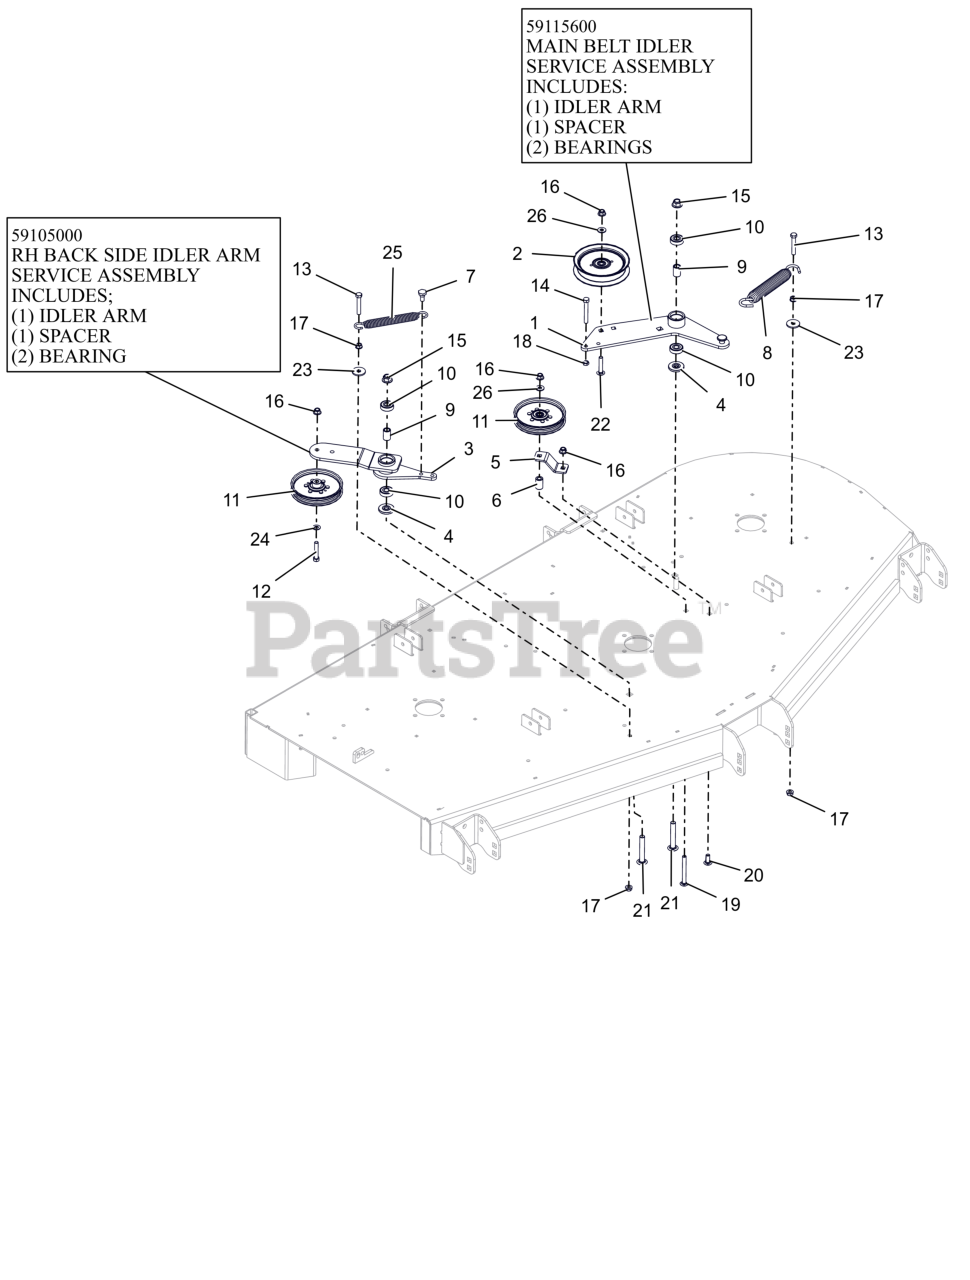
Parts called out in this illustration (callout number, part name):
1	WLDMT, DECK PTO IDLR ARM
1	ASSEMBLY, MAIN BELT IDLER
2	IDLER, FLAT 5.00"
3	WLDMT, DECK RH IDLER ARM
3	RH BACKSIDE IDLER ARM ASSEMBLY
4	SPACER, IDLER ARM
5	PTO FIXED IDLER MTG BRKT -RED
6	BUSHING, SLV .380X.750X1.190
7	BLT,SHLDR EP .38-16X.30 HEX YZ
8	SPRING, EXTENSION
9	SPACER .510 X .75 X 1.1485
10	BRG-BALL .500X1.38X.437
11	PULLEY, FLAT IDLER
12	BLT,HEX .38-16X2.00 G5 ZCC
13	BLT,HEX .38-16X2.25 G5 ZCC
14	BLT, HEX .38-16X2.75 G5 ZCC
15	NUT,NYL-FLG .50-13 GF ZCC
16	NUT,NYL-FLG .38-16 GF ZCC
17	NUT, SPNLK-FLG .38-16 G5 ZCC
18	NUT-JAM .375-16 G2 ZCC
19	BLT,RHSSN .38-16X3.50 G5 ZCC
20	BLT,RHSSN .38-16X1.00 G5 ZCC
21	BTL,RHSSN .500-13 X 3.25 G5 ZCC
22	BLT,RHSSN.375-16X2.00 G5 ZCC
23	WSHR,FLT .406X1.375X.135 ZCC
24	WSHR,FLT .406X.812X.065 ZCC
25	SPRING, EXTENSION
26	WSHR,FLT .375X.875X.083 ZCC
